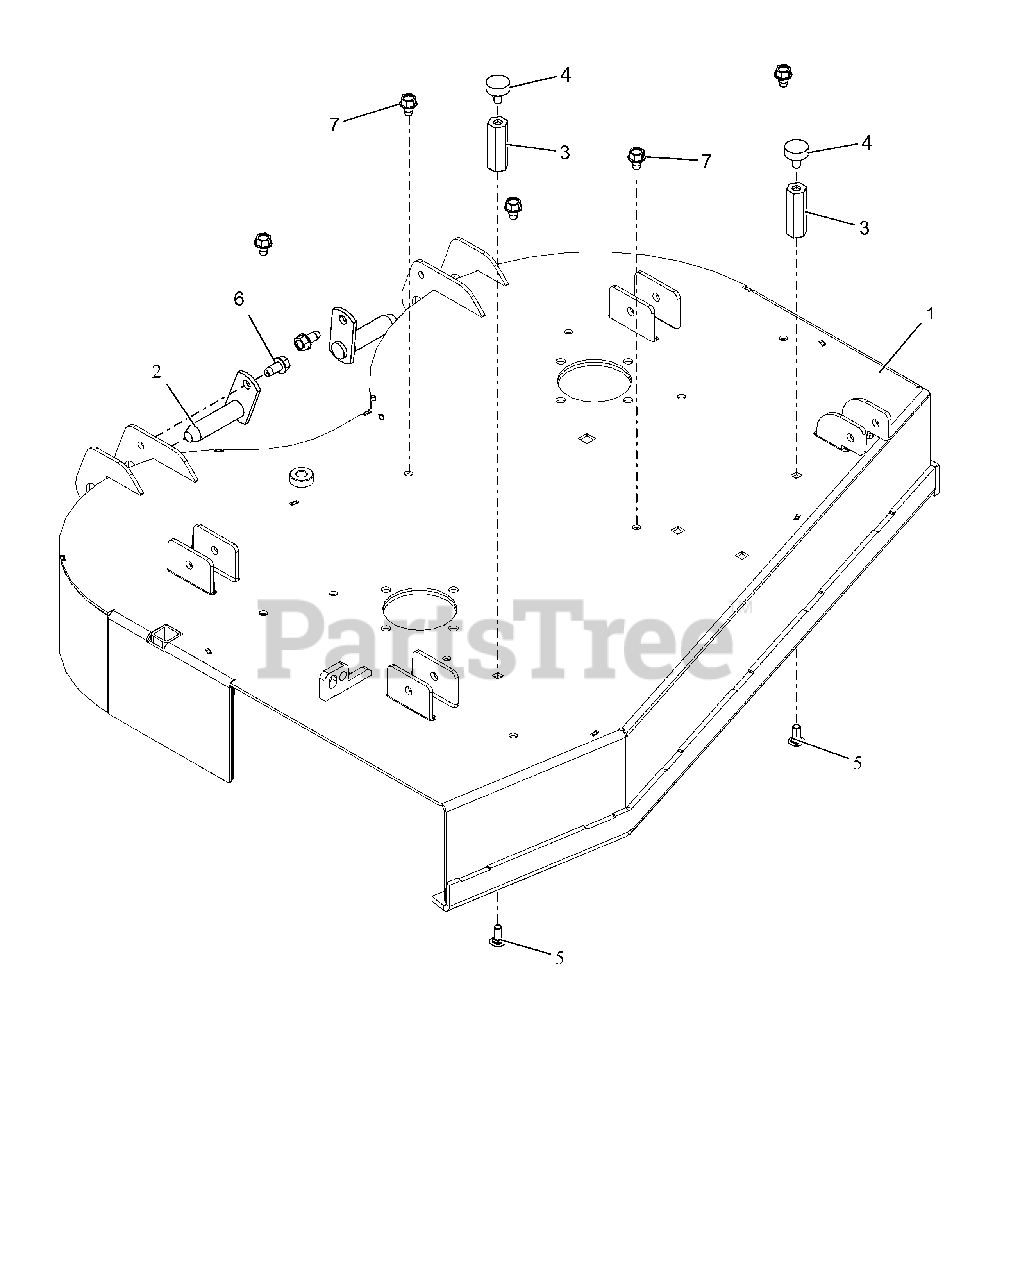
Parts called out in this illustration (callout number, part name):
1	KIT, 36" MOWER DECK W DECALS
2	WLDMT, MOWER MTG. PIN (BLACK)
3	NUT, .31-18X2.25 LG COUPLING
4	BUMPER, RUBBER
5	BLT,RDHDSQNK .31-18X.75 LOCTIT
6	@SCR-TAP .38-16X.75 HWH TR YWZ
7	@SCR-TAP .38-16X.50 HWH TR YWZ
